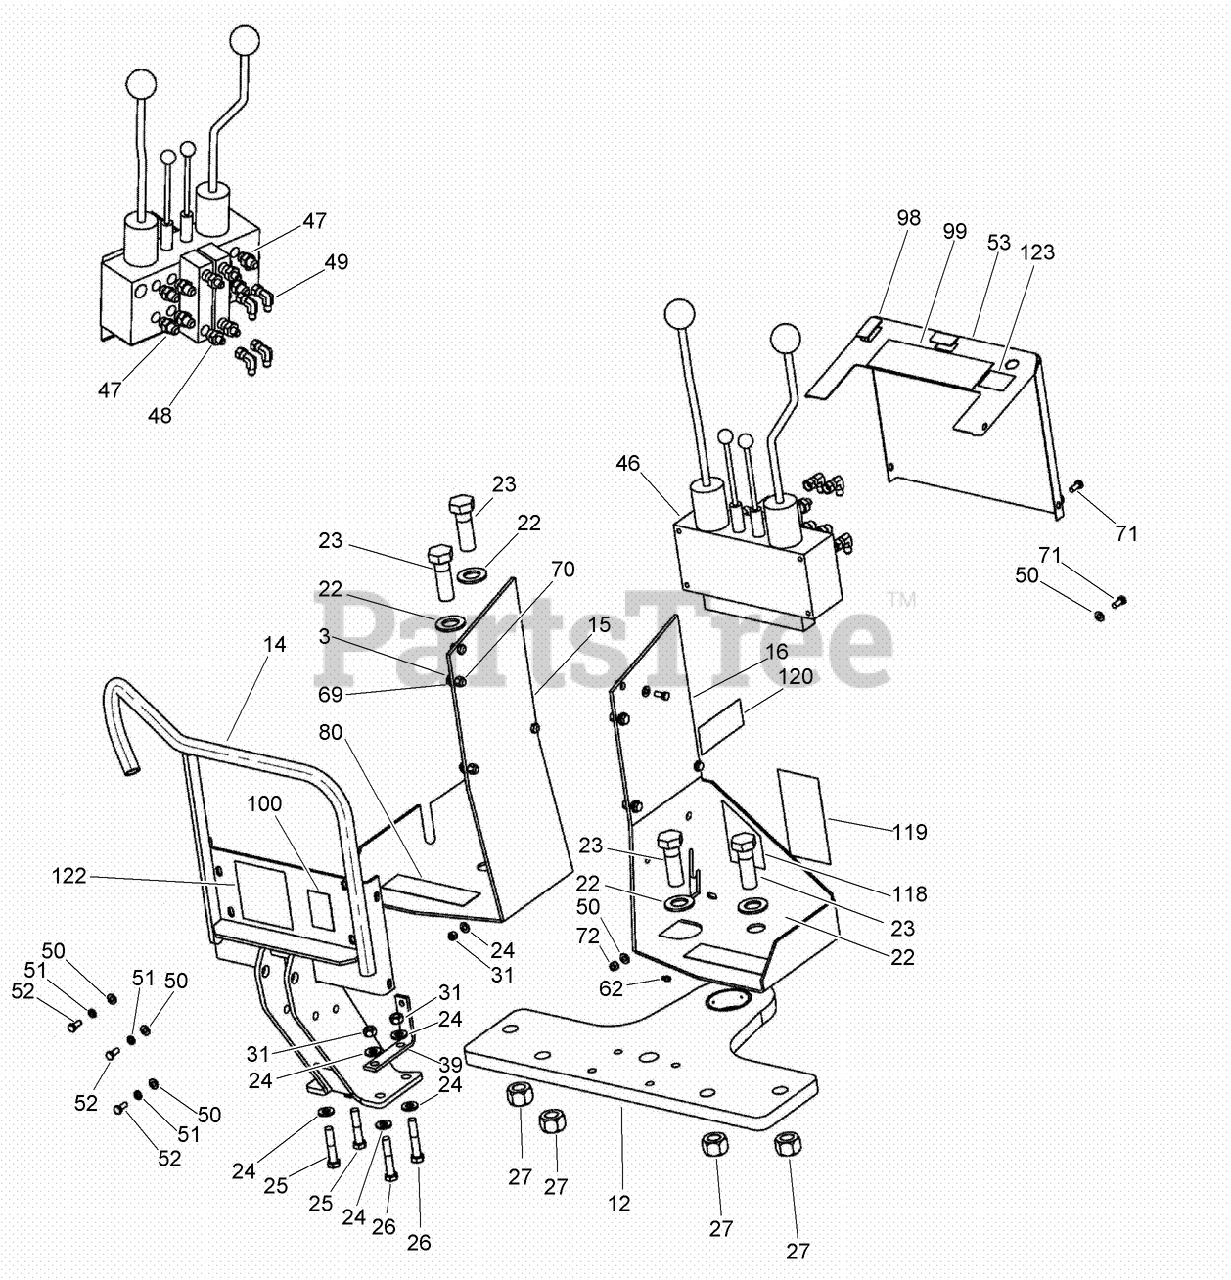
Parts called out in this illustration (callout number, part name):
3	SCREW-HH
12	PLATE ASM-Top Pivot
14	CONSOLE-Valve Mounting
15	GUARD-Foot, Left-hand
16	GUARD-Foot, Right-hand
24	WASHER-FLAT
25	SCREW-HH
26	BOLT-Hex, 1/2 NC x 2-3/4 inch
27	NUT-HEX LOCK
31	NUT-LOCK, HEX
39	ANGLE-Handle Spt
46	HYD CONTROL VALVE ASM
47	CONNECTOR-Str Thd 1/2, 37FL-ORB 1/2
48	CONNECTOR
49	ELBOW-SWIVEL, 90 DEG
50	WASHER-FLAT
51	WASHER-Lock, 5/16 inch
52	BOLT-Hex, 5/16 NF x 3/4 inch
53	COVER-Backhoe Valve, with Opening at Bottom
62	FITTING-Lube 1/4-28 Tpr SAE-LT .54 Long
69	WASHER-FLAT
70	NUT-HEX
72	NUT-HEX
80	STRIP-Anti-skid, Backhoe Access Steps
98	BLANK-SWITCH, ROCKER
99	DECAL-Backhoe Control Pattern
100	DECAL-Read Operators Manual
118	DECAL-Swing Lock
119	DECAL-Danger, BH Crush Hazard
120	DECAL-Danger, BH Crush Hazard
122	DECAL-Warning, Lifting with Backhoe
123	DECAL-Engine Shut-Off
